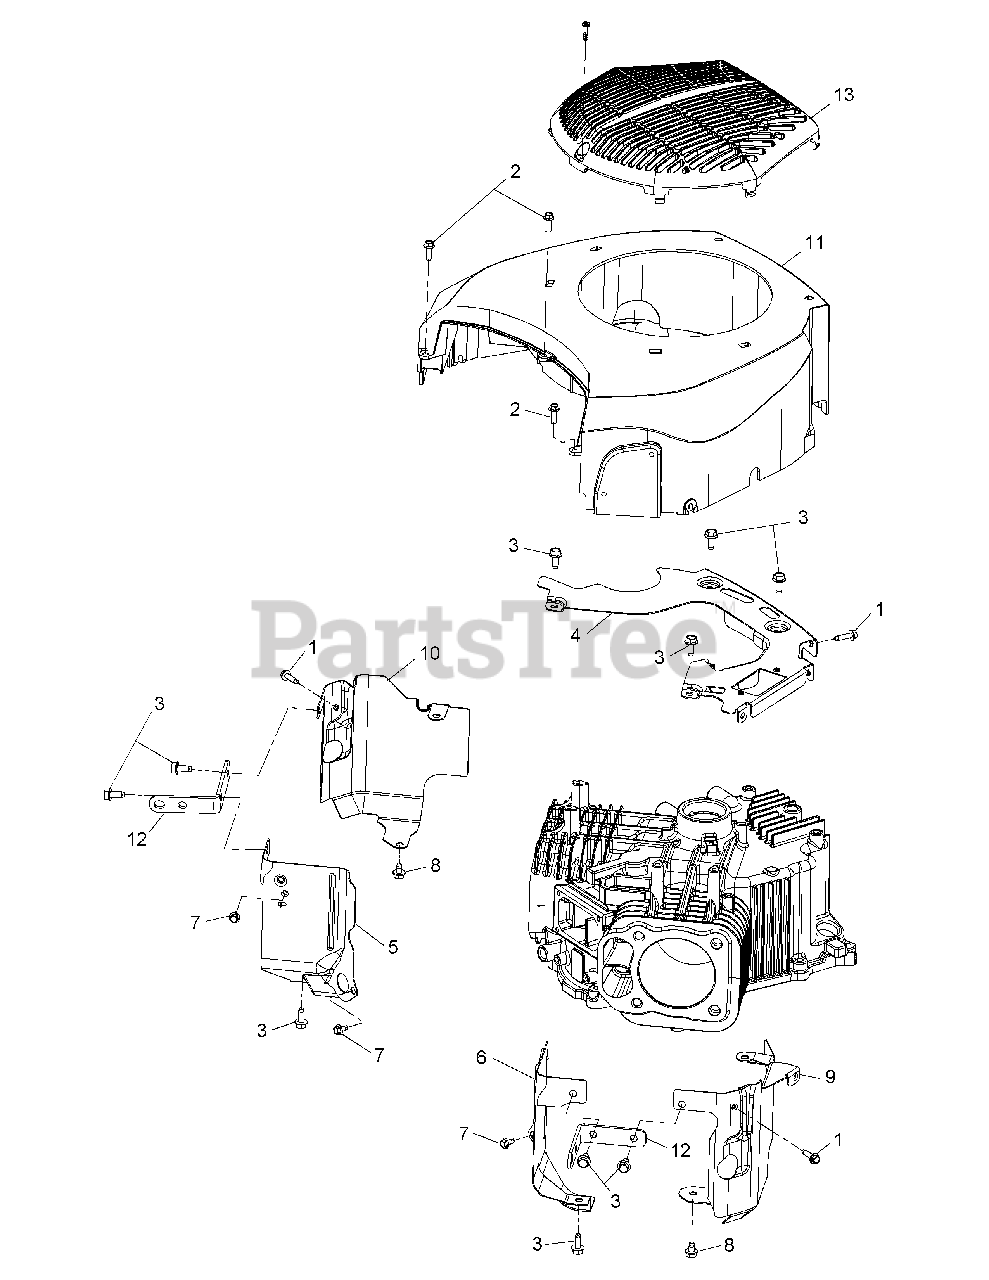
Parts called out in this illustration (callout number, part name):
1	Thread Forming Screw
3	Thread Forming Screw
4	Backing Plate
5	Valley Baffle, #1 Cylinder
6	Valley Baffle, #2 Cylinder
7	Thread Forming Screw
8	Thread Forming Screw
9	Left Barrel Baffle
10	Right Barrel Baffle
11	Blower Housing
